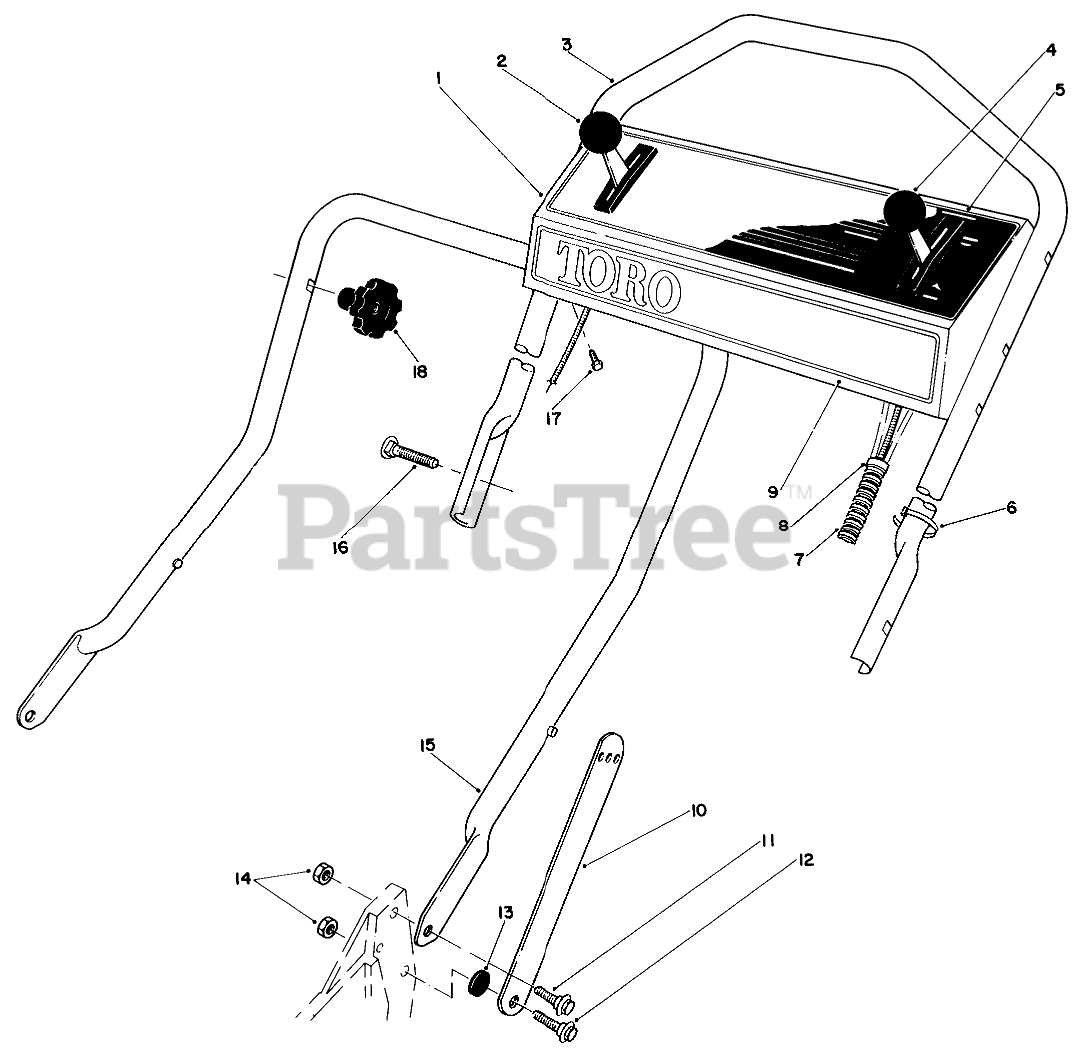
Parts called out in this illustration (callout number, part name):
1	Panel-Control (Incl. Ref. #5)
2	GROUND SPEED CONTROL
3	Handle-Upper
4	SERVICE THROTTLE CONTRO
5	Decal-Instruction Panel
6	TIE-CABLE
7	CONTROL CABLE COVER
8	FITTING-RING
9	Decal-Toro
10	Handle Latch
11	SCREW-SHOULDER
12	SCREW-SHOULDER
13	SPACER
14	NUT-LOCK, NI
15	Handle-Lower
16	5/16-18 X 2 HNDLE SCREW
17	SCREW-HWHTF
